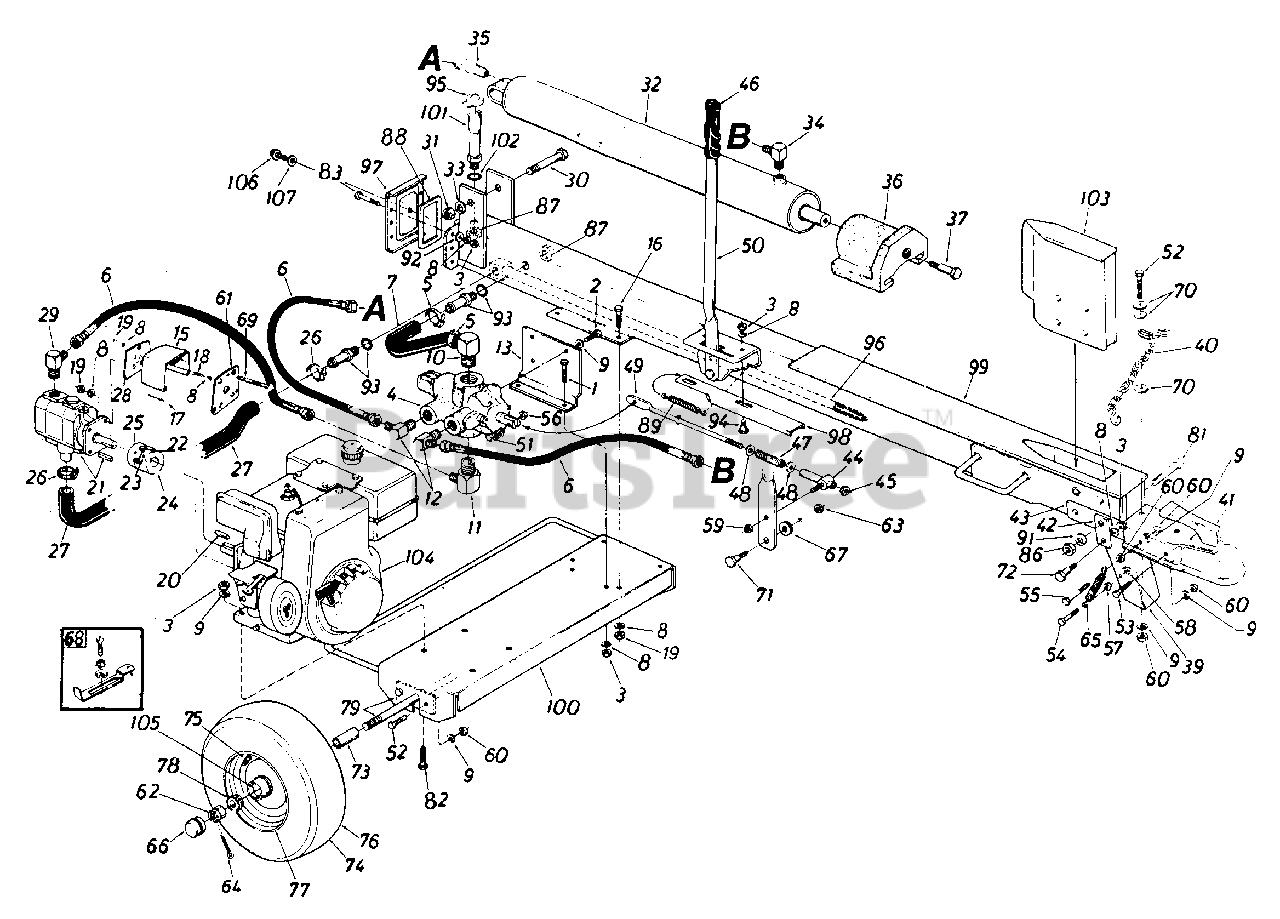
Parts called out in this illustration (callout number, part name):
1	SCREW-HEX 5/16-18 X .75
2	SCREW-HEX 3/8-16 X .50
3	NUT-HEX 5/16-18
4	VALVE-CONTROL
5	CLAMP-HOSE-5/8
6	HOSE ASSY-PRESSURE
7	HOSE-RETURN
8	WASHER-LOCK-5/16
9	WASHER-LOCK-3/8
10	ELBOW-RETURN
11	ADAPTER-90 DEGREE
12	ADAPTER-90 DEGREE
13	PLATE-MTG-VALVE
15	SHIELD-COUPLING
16	SCREW-HEX SPECIAL 5/16-24X1.0
17	SCREW-HEX 5/16-24 X .75
18	SCREW-HEX 5/16-24 X .62
19	NUT-5/16-24
20	KEY-SQ 3/16X2.25
21	PUMP
22	SPIDER-L-090-COUPLING-LOG SPLITTER
23	SCREW-SET 1/4-20 X .25 CUP
24	COUPLING HALF
25	COUPLING-HALF
26	CLAMP-HOSE-5/8
27	HOSE ASSY-SUCTION
29	ADAPTER-90 DEGREE
30	SCREW-HEX 3/4X4.0
31	NUT-HEX 3/4
32	CYLINDER-HYDRO
33	WASHER
34	ELBOW-HIGH PRESSURE
36	PLATE-PUSH
37	SCREW-SHLD .62X.475
39	BRACKET-FLIP STAND
40	CHAIN-TOW HITCH
41	HITCH ASSY-TOW
42	BRACKET-PIVOT
43	BRACKET-TOW HITCH
44	FERRULE ASSY
45	NUT-HEX INS L 3/8 X 24
46	GRIP-LIFT HANDLE
47	SPRING-BRAKE
48	WASHER-SPEC .378 X 1.00 X .125
49	ROD-ENGAGEMENT
50	HANDLE-ENGAGEMENT
51	SCREW-HEX 1/4-20 X 1.25
52	SCREW 3/8-24X1.25 GR5
53	SCREW-HEX 3/8-24 X .75
54	SCREW-HEX 1/4-28 X 1.00
55	SCREW-HEX 3/8-24 X 1.75
56	NUT-HEX CENTER L-1/4-20
57	NUT-HEX CENTER L-1/4-28
58	NUT-HEX 1/4-28
59	NUT-HEX CENTER L-5/16-18
60	NUT-HEX 3/8-24
62	NUT-HEX CASTLE
63	NUT-HEX CENTER L-3/8-16
64	PIN-COTTER-5/32 DIA
65	SPRING-EXTENSION
67	WASHER-RUBBER .50 X 1.00 X .25
68	CONTROL-THROTTLE B&S 5 HP
69	SCREW-HEX 5/16-24 X 4.00
70	WASHER-FL-.385 ID X .87 OD X .06
71	SCREW-SHLD .498 DIA X .340
72	SCREW-SHLD .437 DIA X .265
75	VALVE-TUBELESS AIR
76	TIRE-PNEU 16.0X4.0
78	BEARING-ROLLER-3/4 IN
79	AXLE ASSY
81	SCREW-HEX 5/8-18 X 3.50
82	SCREW-HEX 5/16-24 X 1.75
83	SCREW-HEX 5/16-18 X 1.50
86	NUT-HEX 5/8-18
87	NUT-HEX 1 1/16-12
89	SPRING-EXTENSION
91	WASHER-LOCK-5/8
92	WASHER-FL (#46041)
94	SCREW-SHLD .437 DIA X .180
95	CAP ASSY-GAS
96	TUBE ASSY-STRAINER
97	PLATE-END
98	BRACKET-ENGAGE
99	TANK ASSY
100	FRAME ASSY
101	TUBE ASSY-FILLER
103	WEDGE ASSY
105	RETAINER-GREASE
106	SCREW-HEX WASH HD 5/16-18
107	WASHER-GASKET
